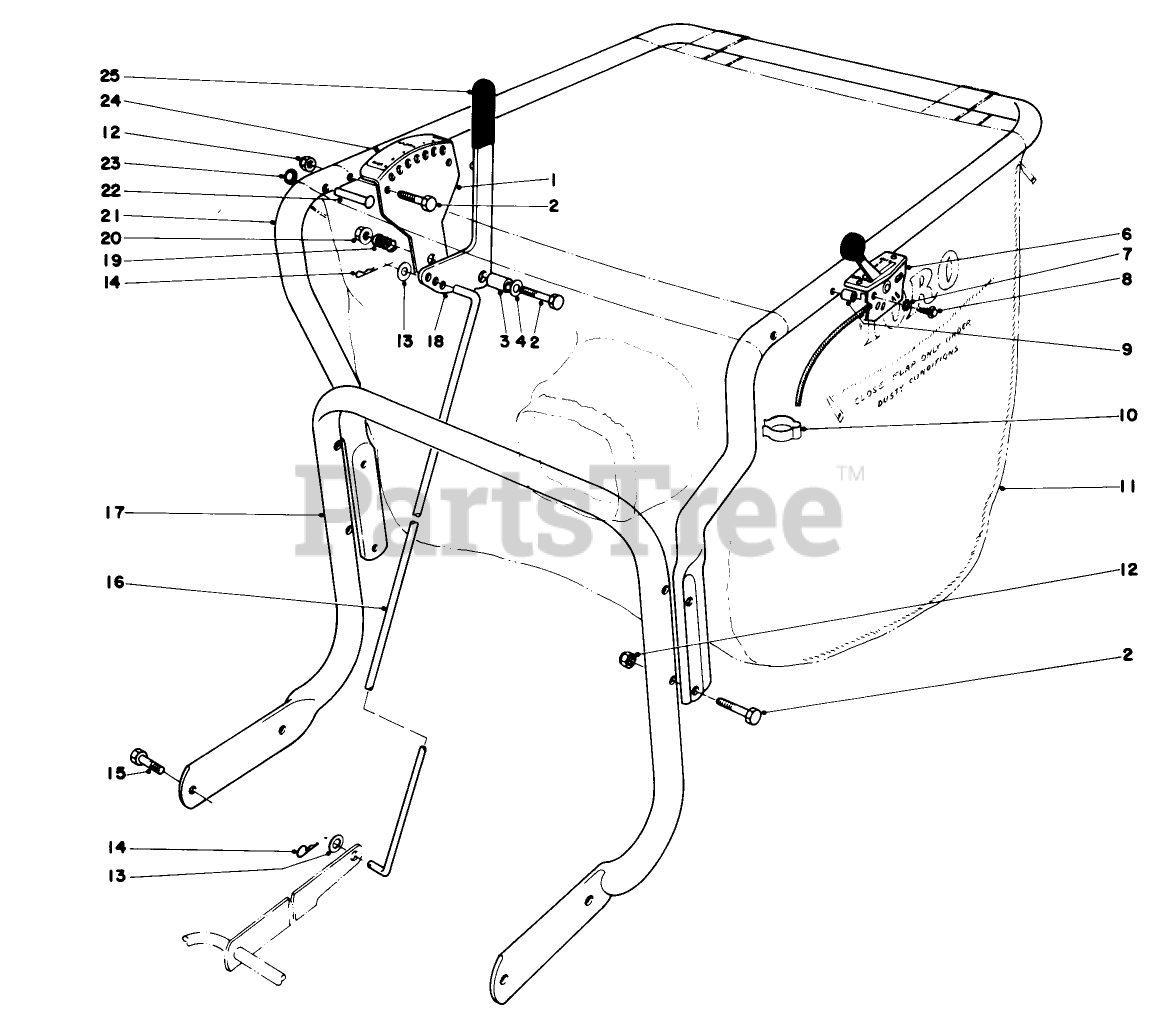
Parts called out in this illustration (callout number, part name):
2	SCREW-HH
3	SPACER
4	WASHER-FLAT
7	WASHER-LOCK, EXT
9	SPACER
12	NUT-LOCK, CONE
13	WASHER-FLAT
14	PIN-COTTER
15	SCREW-HH
16	HEIGHT ADJ. ROD
17	HANDLE
19	SPRING-COMPRESSION
20	NUT-HF
21	HANDLE-UPPER, VACUUM
22	RIVET
23	RING-RETAIN,PUSH,EXT,FLAT
25	GRIP-HANDLE
